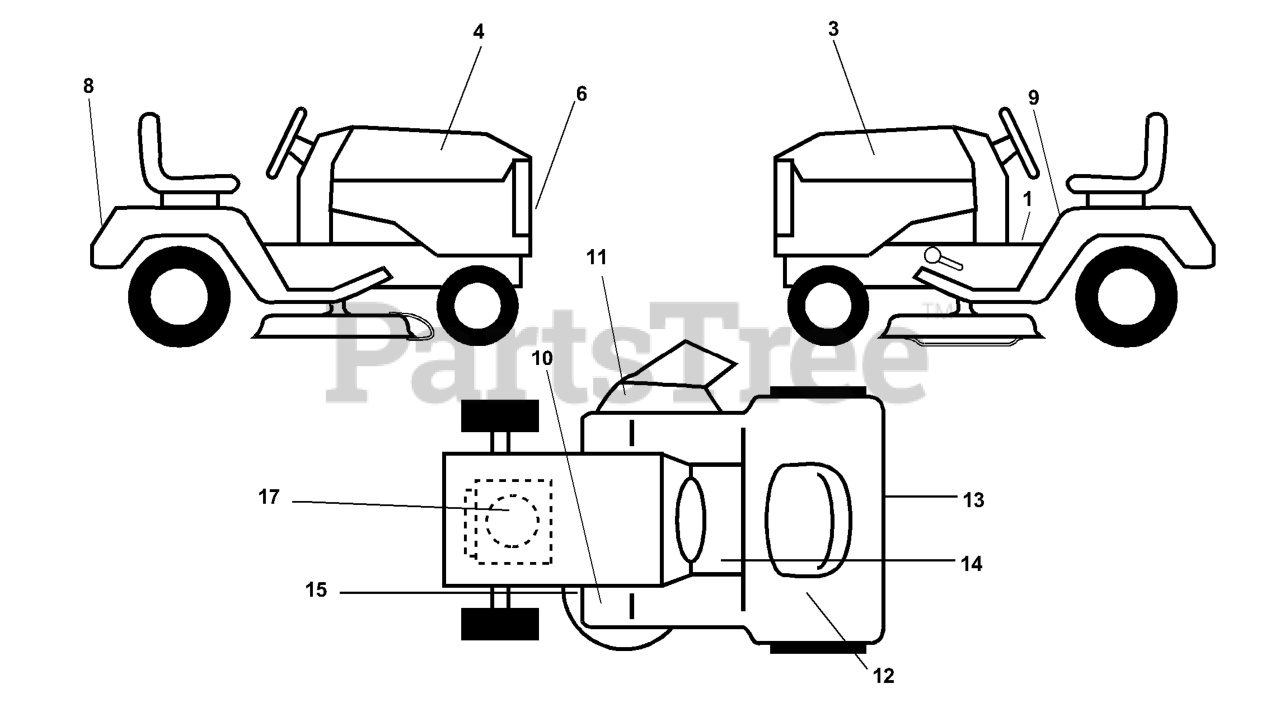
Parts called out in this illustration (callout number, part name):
1	DECAL DASH
3	DECAL HOOD LH
4	DECAL HOOD RH
6	DECAL.GRILLE.HUSQ
8	DECAL FENDER HUSQ
9	DECAL CAUTION
11	DECAL WARNING (ENGLISH/FRENCH)
12	DECAL BTRY SYMBOLS
13	DECAL DRAWBAR CONTROL
15	DECAL V-BELT SCHEMATIC
17	DECAL HP ENGINE
